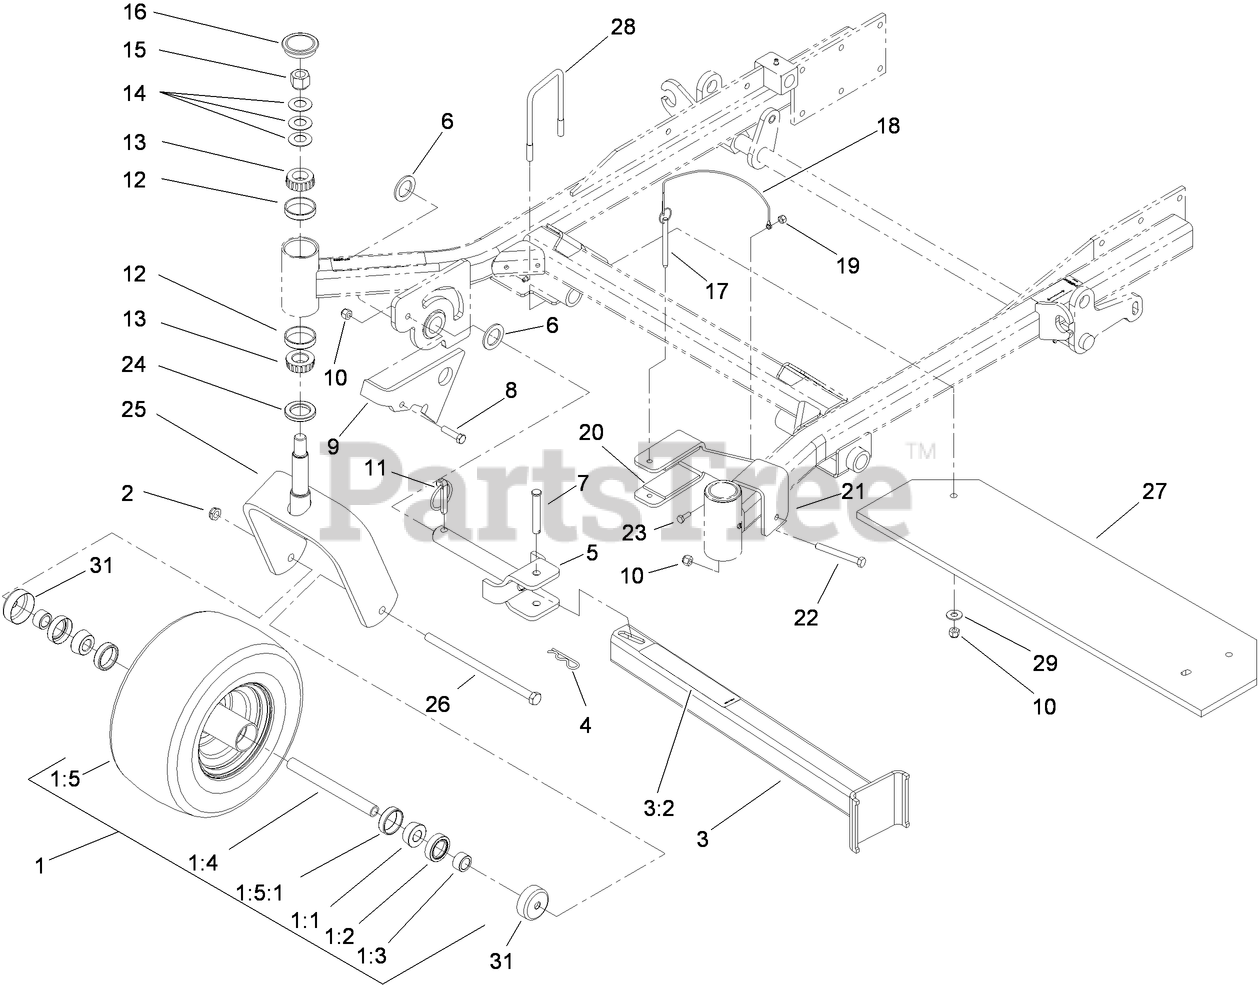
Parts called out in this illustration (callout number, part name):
1	WHEEL AND TIRE ASM
1:1	BEARING-CONE, TAPER
1:2	SEAL-CASTER
1:3	SPACER-NUT
1:4	AXLE-CASTER
1:5	WHEEL AND TIRE ASM
1:5:1	BEARING-CUP
2	NUT-LOCK, NI
3	Leg ASM
3:2	DECAL-Z STAND
4	PIN-HAIR
5	PIN-PIVOT
6	WASHER-THRUST
7	PIN-CLEVIS
8	SCREW-HH
9	BRACKET-LATCH
10	NUT-LOCK, NI
11	PIN-LYNCH
12	BEARING-CUP, TAPERED
13	BEARING-CONE, TAPERED
14	WASHER-BELLVILLE
15	NUT-LOCK, NI
16	CAP-GREASE
17	PIN-HITCH, COTTERLESS
18	LANYARD-NYLON
19	NUT-LOCK, NI
20	Cushion-Rubber
21	BRACKET-CRADLE
22	SCREW-HH
23	SCREW-HH
24	SEAL-GREASE
25	CASTER-FORK
26	Screw-HH
27	BAR-WEIGHT
28	U-BOLT, 3IN
29	WASHER-FLAT
31	GUARD-SEAL
